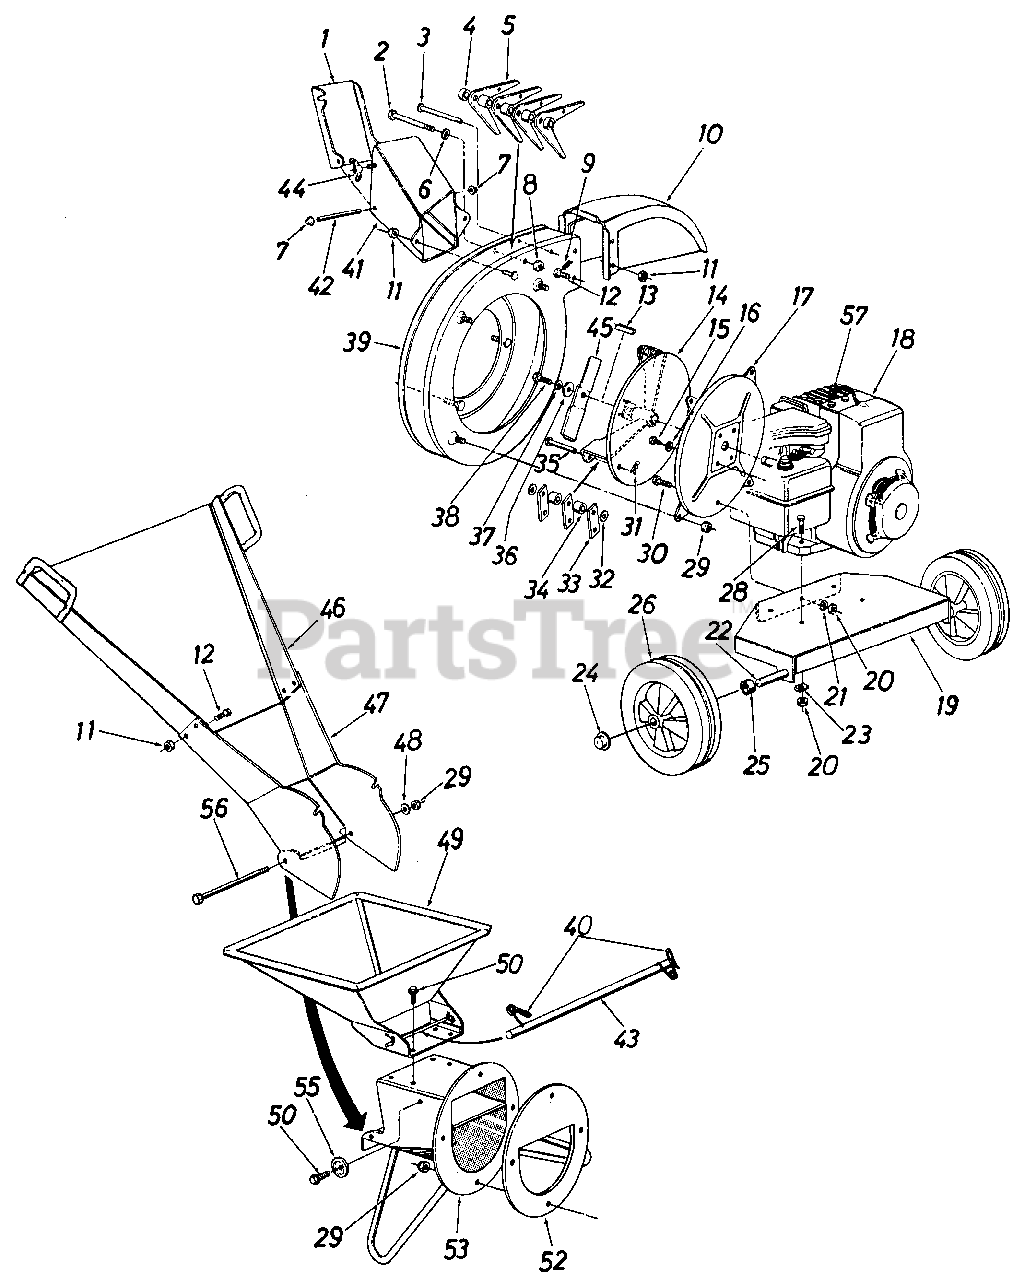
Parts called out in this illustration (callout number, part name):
2	SCREW-HEX 1/2-20 X 4.50
3	PIN-CLEVIS-5/16 X3 5/8
5	CUTTING FINGER
6	WASHER-LOCK-1/2
8	NUT-HEX JAM 1/2-20
9	PIN-COTTER-3/32 DIA X .75
10	DEFLECTOR-CHUTE
11	NUT-HEX CENTER L-1/4-20
12	SCREW-HEX 1/4-20 X .50
13	KEY-SQ 1/4 X 2.00
14	IMPELLER ASSY-COMP
15	SCREW-HEX 5/16-24 X .75
16	WASHER-LOCK-5/16
17	PLATE-MTG
19	PLATE-ENGINE MTG
20	NUT-5/16-24
21	WASHER-LOCK-5/16
23	WASHER-SPEC L 5/16 X .88 OD
26	WHEEL ASSY W/TIRE-10 X 2.50
28	SCREW-5/16-24 X 1.5
29	NUT-HEX INS L-5/16-18
30	SCREW-HEX 5/16-24 X .62
31	PIN-COTTER-1/8 DIA X 1
32	WASHER-FL-.531 ID X .93 OD X .090
33	FLAIL
34	SPACER-FLAIL
35	PIN-CLEVIS-1/2 X 3
36	WASHER-FL-HOND .410ID X 1.255X.162
37	WASHER-HDL 3/8
38	SCREW-HEX 3/8-24 X 2.00
41	EXTENSION ASSY-GUARD
42	PIN-HINGE
43	BAR-RELEASE
44	NUT-INS WING L-1/4-20
47	RAMP-SECTION-LWR LEAF
48	WASHER-FL-.344 X .62
49	HOPPER ASSY
50	SCREW-HEX WASH SF TAPP
52	PLATE-BACK-UP
53	GUIDE ASSY-INLET
55	WASHER-STOP
56	SCREW-HEX 5/16-18 X 8.25
57	INSULATOR-SPARK PLUG
